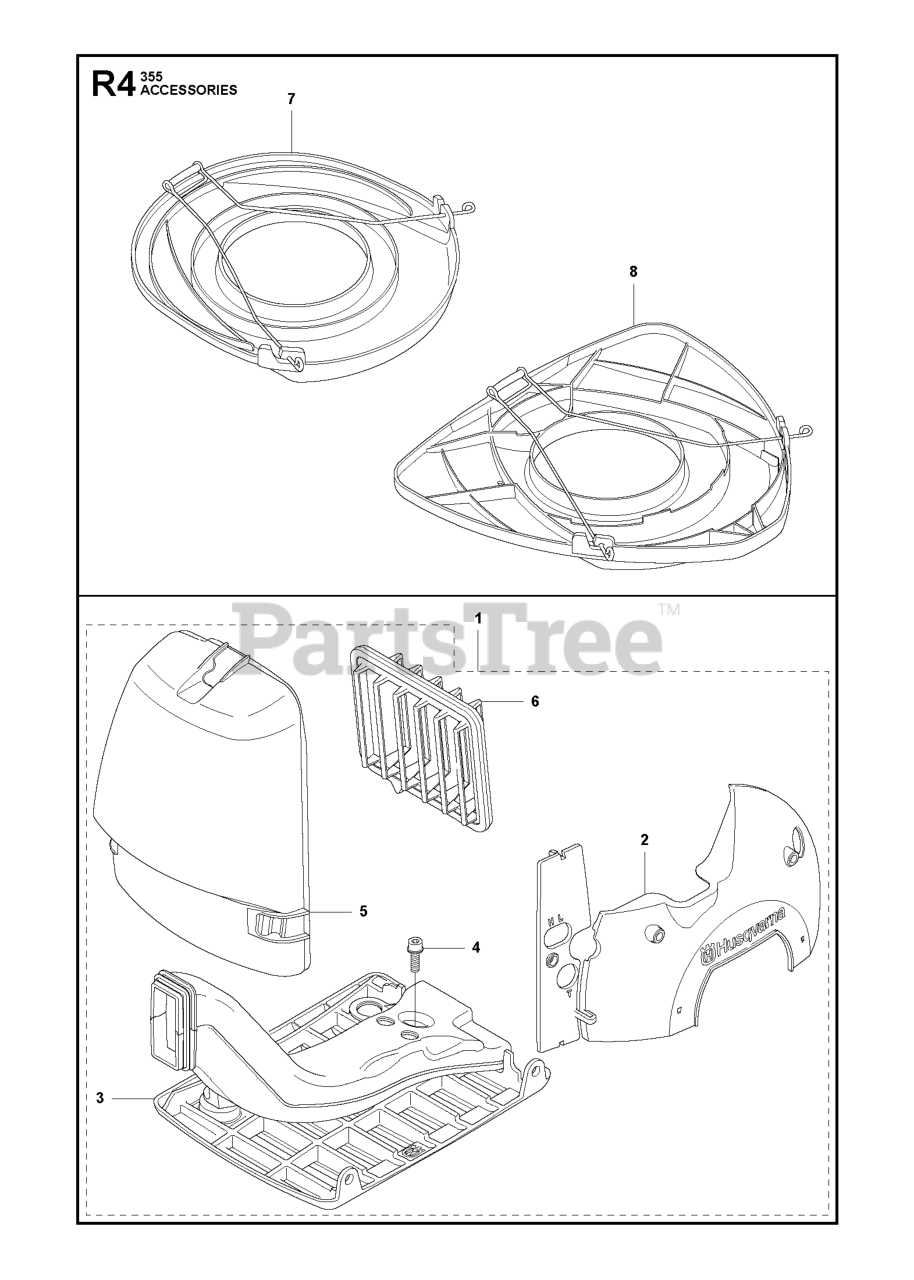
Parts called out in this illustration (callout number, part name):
1	WINTER KIT
2	WINTER COVER
7	BLADE GUARD TRANSPORT
8	TRANSPORT GUARD
